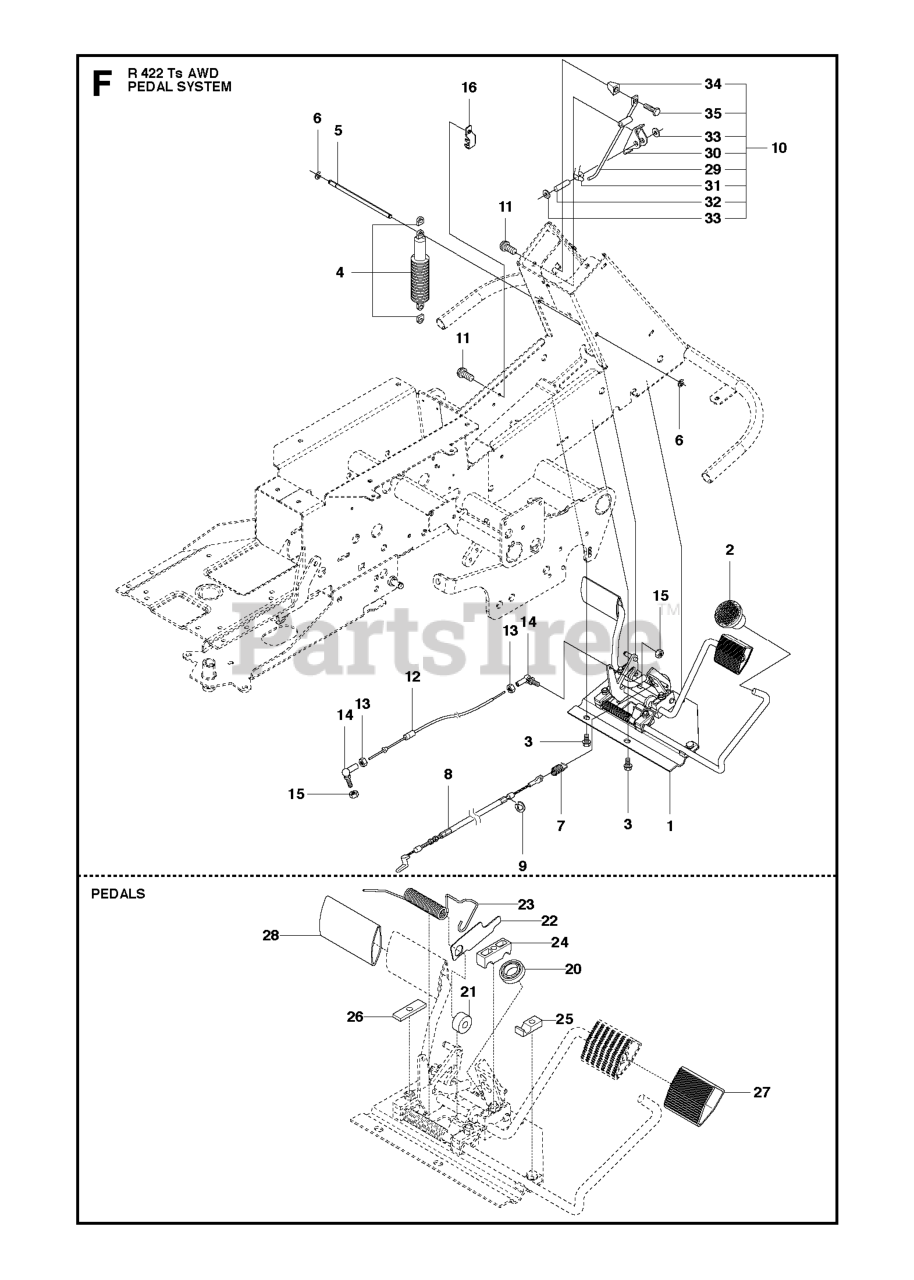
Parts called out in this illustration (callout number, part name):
1	PEDAL ASSEMBLY
2	KNOB
4	SHOCK ABSORBER
8	BRAKE WIRE
12	CONTROL CABLE
14	CONNECTOR
15	LOCKNUT M5
16	BRACKET
20	BALL BEARING 6002-2RS1
21	ROLLER
22	PLATE
23	SPRING
24	PEDAL SHAFT CLAMP
25	SUPPORT
26	PLATE
27	PEDAL RUBBER
28	PEDAL RUBBER, SF
